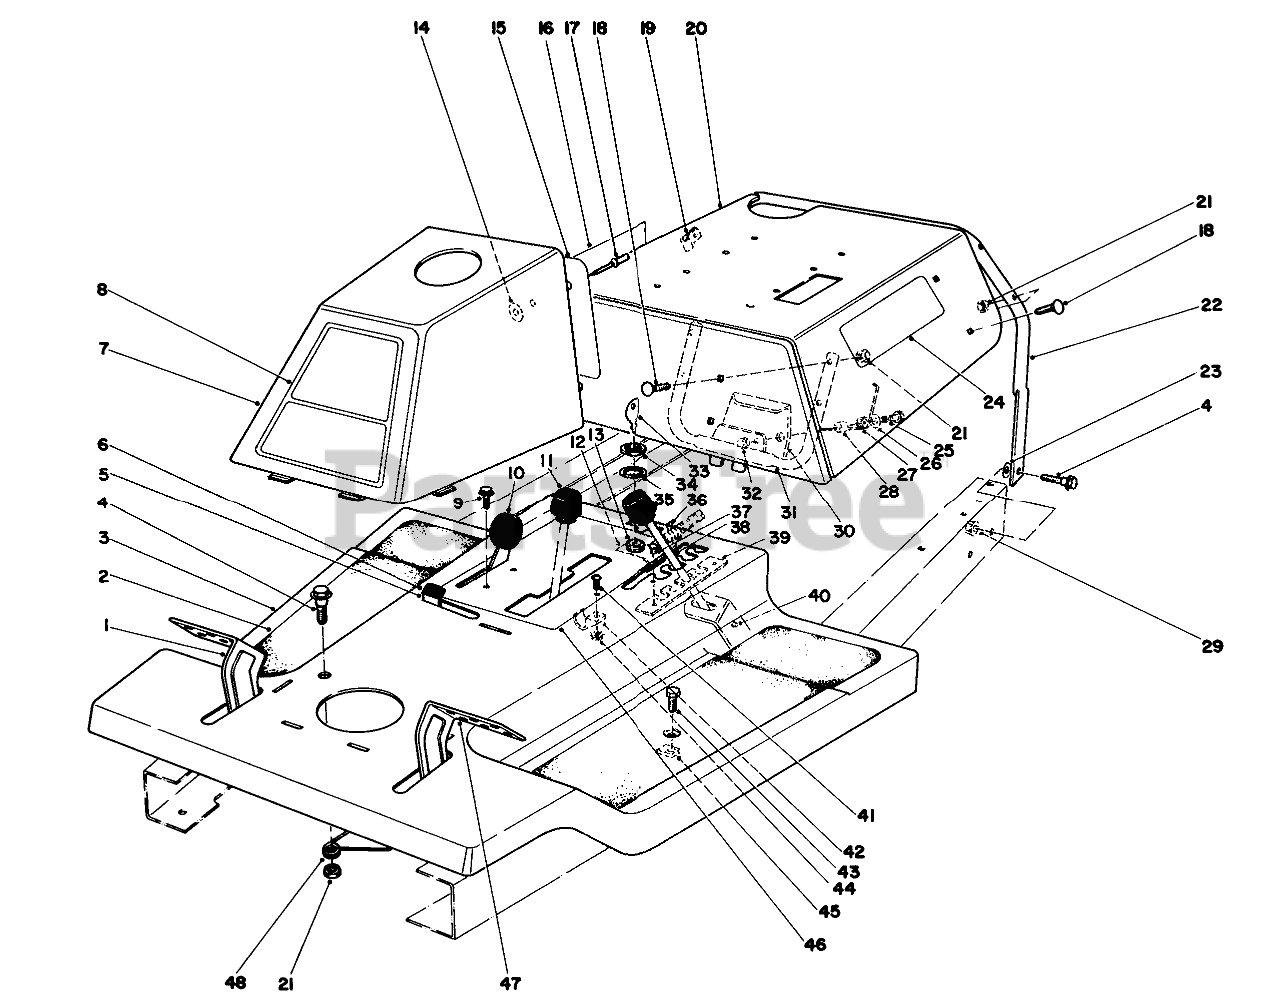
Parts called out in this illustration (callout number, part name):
1	Brake Pedal
2	TREAD-FOOT
3	Front Body Assembly (Incl. Ref. #37, 39, & 46)
4	SCREW-SHOULDER
5	Parking Brake
6	TIP-PARKING BRAKE
7	Tower (Incl. Ref. #14, 15, & 17)
8	725 DECAL
9	8X1/2 SELF TAP SCREW
10	THROTTLE CONTROL ASM
13	Switch-Starter (Incl. Ref. #33-35)
14	WASHER-PLAIN
15	Decal-Tower
16	Decal Shift Pattern
18	BOLT-CARR
19	CLIP-FUEL LINE
20	Body-Rear
21	NUT-LOCK, NI
22	Support-Rear Body
23	WASHER-PLAIN
24	Decal
25	SCREW-HH
26	WASHER-FLAT
27	Spring-Latch
28	LATCH SPACER
29	NUT-HF
30	Latch
31	Front Support
32	NUT-CAP
33	Key
34	NUT-HH
35	WASHER-TOOTH, INTERNAL
36	TIE-CABLE
37	RIVET-POP
38	Height of Cut Lever
39	Height Adjustment Plate
40	PIN-ROLL
42	WIRE CLAMP
43	SCREW-HH
44	NUT-KEPS
45	NUT-TINNERMAN
46	DECAL
47	Clutch Pedal
48	SPRING-PARKING BRAKE
